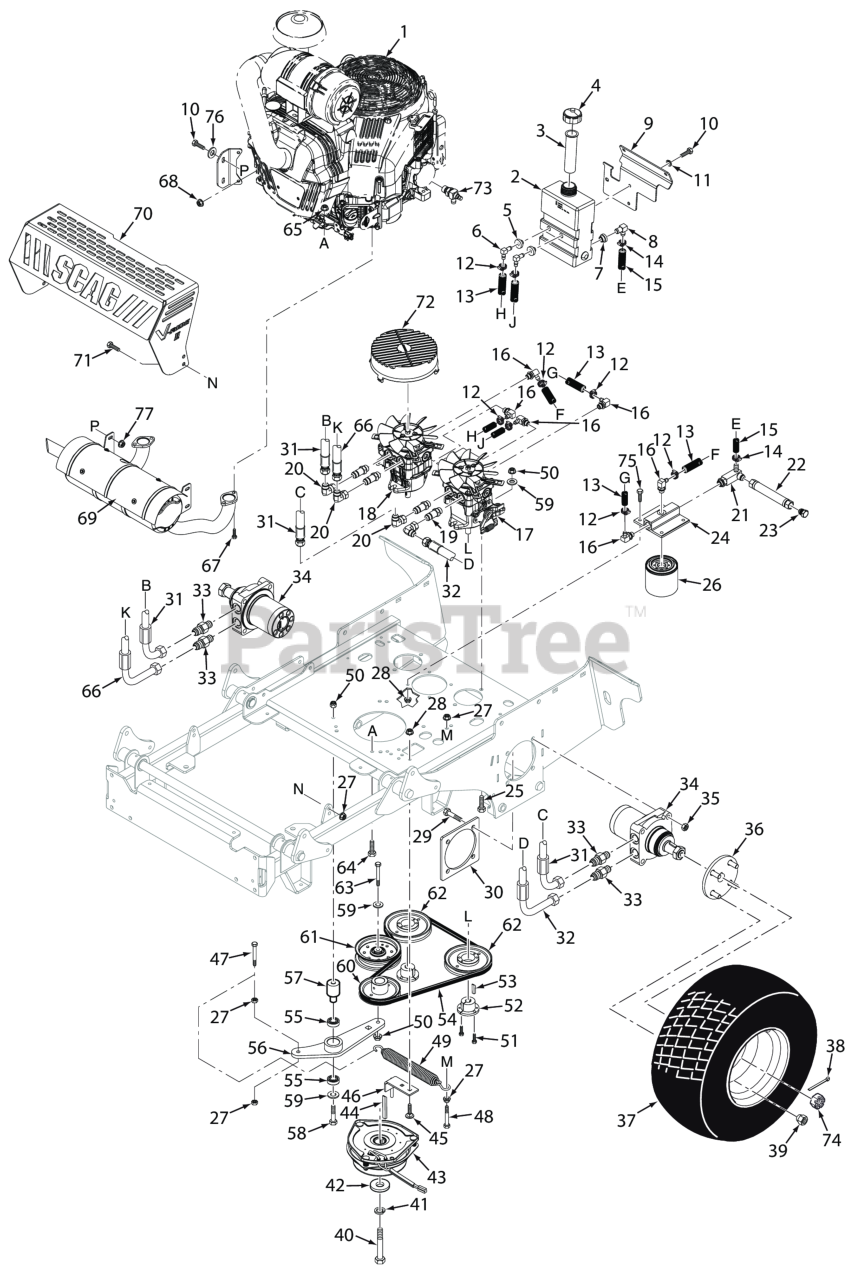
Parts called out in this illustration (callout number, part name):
1	Engine, Briggs & Stratton 37 BV-EFI (61E8770002J1)
2	Hydro Tank Assy., SVRII
3	Insert, Filler Neck
4	CAP, HYDRAULIC TANK
5	Bushing, 0.56" Dia. Viton
6	Elbow, 90 Degree, 9/16-18 JIC x 9/16 O-Ring
7	Bushing, 0.78" Dia. Viton
8	Fitting, 90 Degree - 1/2" Hose
9	Bracket, Hydro Tank Mounting
10	BOLT, SERRATED FLANGE HEX HEAD 5/16-18 X 3/4"
11	Lockwasher, 5/16 (.317 x .586 x .078) Helical Spring
12	Clamp, .69" Max. / .25" Min. Dia.
13	Hose, 3/8" ID - 10-1/4" Long (Order By The Inch)
14	Clamp, Cable 3/4" I.D.
15	Hose Assembly, 1/2" ID (Oil Reservoir to Filter Base)
16	Elbow, 90 Degree - 9/16" O-Ring x 3/8" Hose
17	Pump, LH - SVRII
18	Pump, RH - SVRII
19	Union, O-Ring to JIC
20	Elbow, 1/2 JIC Female to 1/2 JIC Male
21	Tee, 3/4" O-Ring
22	Drain, Hose Assembly
23	Plug, JIC 3/4-16 UNF
24	Filter Head Assembly
25	Bolt, Hex Head, 3/8-16 x 1-1/2"
26	OIL FILTER, SPECIAL
27	NUT, 3/8-16 SERRATED FLANGE HEX HEAD
28	Nut, Serrated Flange 5/16-18 (Right Front Engine Mounting, Briggs and Kohler Only)
29	Bolt, Hex Hd. 1/2-13 x 2-1/2" (lower)
30	Plate Weldment, Motor Backing
31	Hose Assy., 27-1/2"
32	Hose Assy., 15-1/4"
33	TUBE UNION, 3/4-16 JIC TO 7/8-14 "O" RING
34	Wheel Motor, SVRII
34	Key, Woodruff 5/16 x 1"
35	Locknut, Hex 1/2-13 Center Lock
36	Wheel Hub Assy., SVRII
36	Bolt, Serr. Flange 1/2-20 x 4.563"
37	Wheel Assembly, 24 x 12-12 (SPZ61)
37	Tire, 24 x 12-12 (SPZ61)
37	(52") Rim 481851 (61") Rim w/Stem
38	Pin, Cotter 9/16" x 1-1/2"
39	Wheel Nut, 1/2-20 x 13/16
40	Bolt, Hex Head 7/16-20 x 2-1/4" w/Patch (Kawasaki)
41	Lockwasher, 7/16� Spring
42	Flatwasher, 7/16-.469 x 1.75 x .25 (48, 52)
43	Clutch w/Tag GT3.5--FE05 (61)
44	Key, 1/4 x 1/4 x 3-1/2"
45	Bolt, 5/16-18 x .75 RHSN Carriage
46	ANTI-ROTATION WLMT, SVRII
47	Bolt, Hex Head 3/8-16 x 1-1/2" Grade 8 Black
48	Bolt, Hex Head 3/8-16 x 3" - 52"
49	Spring, Transmission Idler
50	HEX NUT, ELASTIC STOP LOCK, 3/8-16
51	Bolt, Hex Head 1/4-20 x 1" Grade 8 Black
52	Hub, Tapered, 15mm Bore
53	KEY, 5 MM X 5 MM X 25 MM
54	Belt, Pump Drive (37BV-EFI)
55	BEARINGS, BALL, NEUTRAL RETURN
56	Idler Arm Assy.
57	Pivot, Idler
58	Capscrew, Hex Head 3/8-16 x 3.25"
59	Flatwasher, 3/8 (.391 x .938 x .105 HD) Grade 8
60	Pulley, 4-3/4" OD - 1.125 Bore
61	Pulley, Idler 4-1/2"
62	Pulley, 5.45 OD - Tapered Bore"
63	Bolt, Hex Head 3/8-16 x 2-1/4" - 61"
64	Bolt, Hex Head, 3/8-16 x 1-1/2"
64	Lockwasher, 5/16" Ext. Tooth (Kohler x1)
65	Nut, Flanged Top Lock 3/8-16
66	Hose Assy., 30"
67	Bolt, Hex Head M8 - 1.25 x 20
68	Nut, M6-1.0 Hex Flange
69	Muffler, Vanguard 37 EFI - SVRII
70	Heatshield Muffler - Vanguard 37 EFI
71	Bolt, Hex Head, 3/8-16 x 1 Gr. 5
72	Fan Cover, Pump
73	Oil Drain, 35BV & 37BV-EFI - Briggs & Stratton
73	Tubing, Oil Drain (order by inch)
74	Nut, Hex Castle 1.0-20 UNEF
75	Bolt, Heax Head 5/16-18 x 1" (48V / 52V)
76	Flatwasher, 5/16-.375 x .875 x .083 (35BV & 37BV-EFI)
77	Nut, Flange Head Elastic Stop 5/16-18
